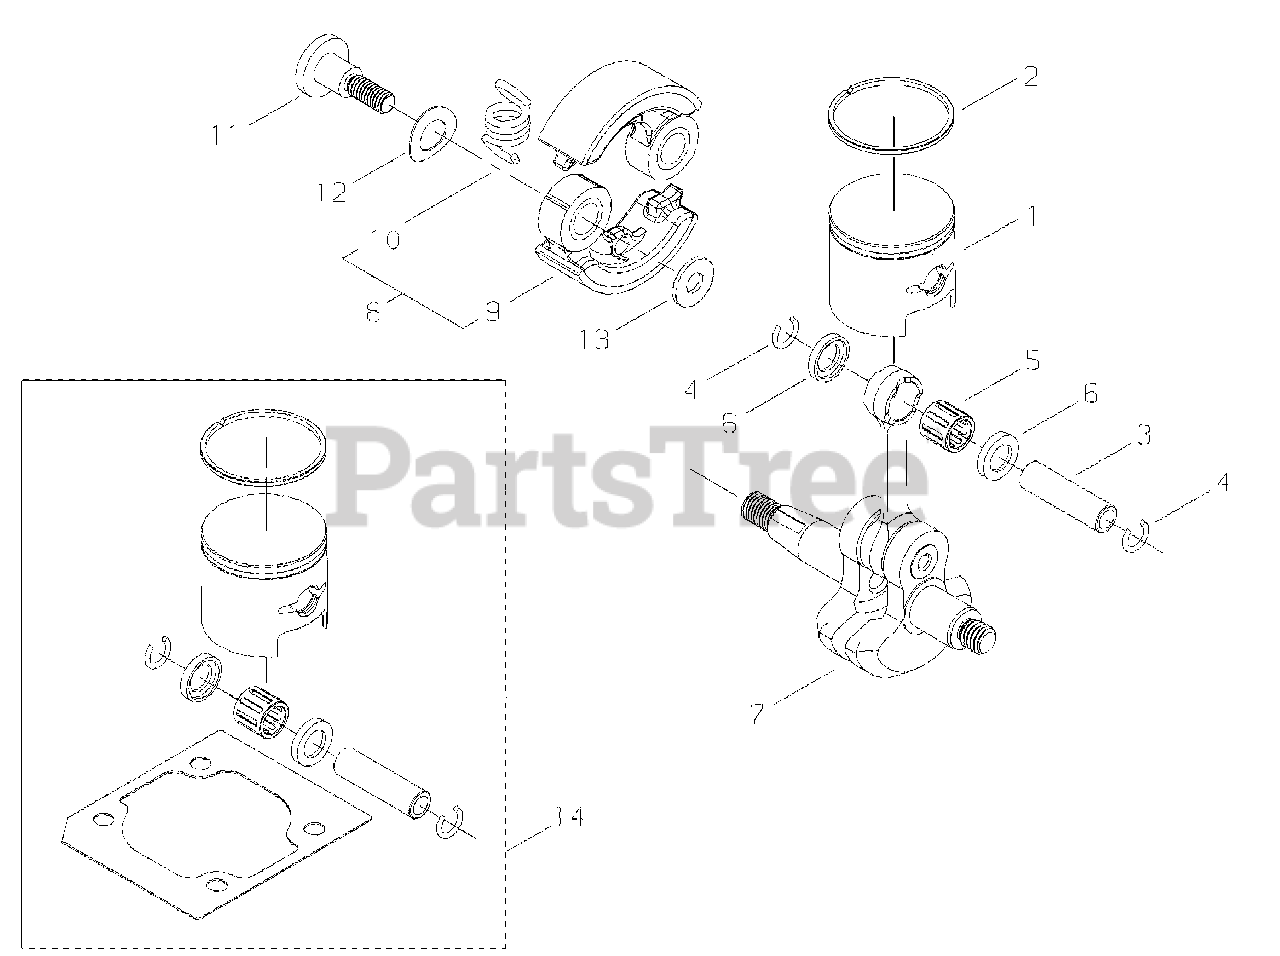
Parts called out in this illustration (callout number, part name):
1	PISTON
2	RING, PISTON
3	PIN, PISTON
4	RING, RETAINING
5	BEARING, NEEDLE - 8
6	SPACER, PISTON
7	CRANKSHAFT ASSY
8	CLUTCH SHOE ASSY
9	SHOE, CLUTCH
10	SPRING, CLUTCH
11	BOLT, CLUTCH
12	WASHER - SPRING
13	WASHER - 6
14	PISTON ASSY
